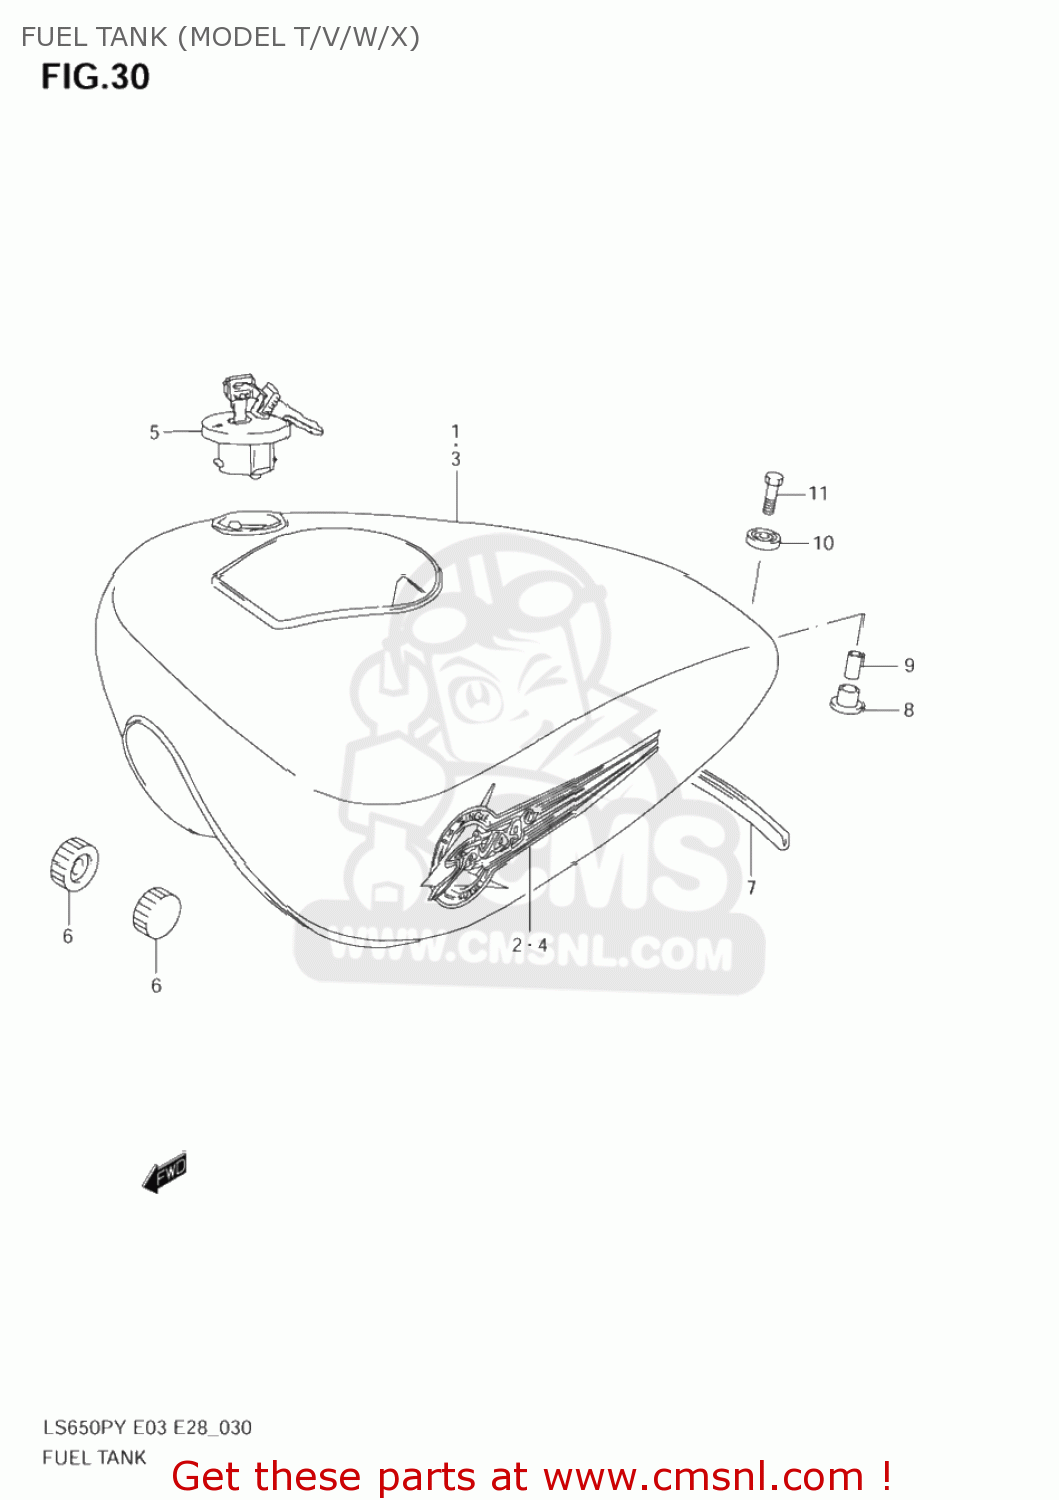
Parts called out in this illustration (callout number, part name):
1	TANK ASSEMBLY,FUEL
2	TAPE SET,FUEL TANK
3	TANK ASSEMBLY,FUEL
4	TAPE SET,FUEL TANK
5	CAP SET,FUEL TANK
6	CUSHION
7	MOLDING,FUEL TANK RR
8	CUSHION
9	SPACER
10	CUSHION
11	BOLT
